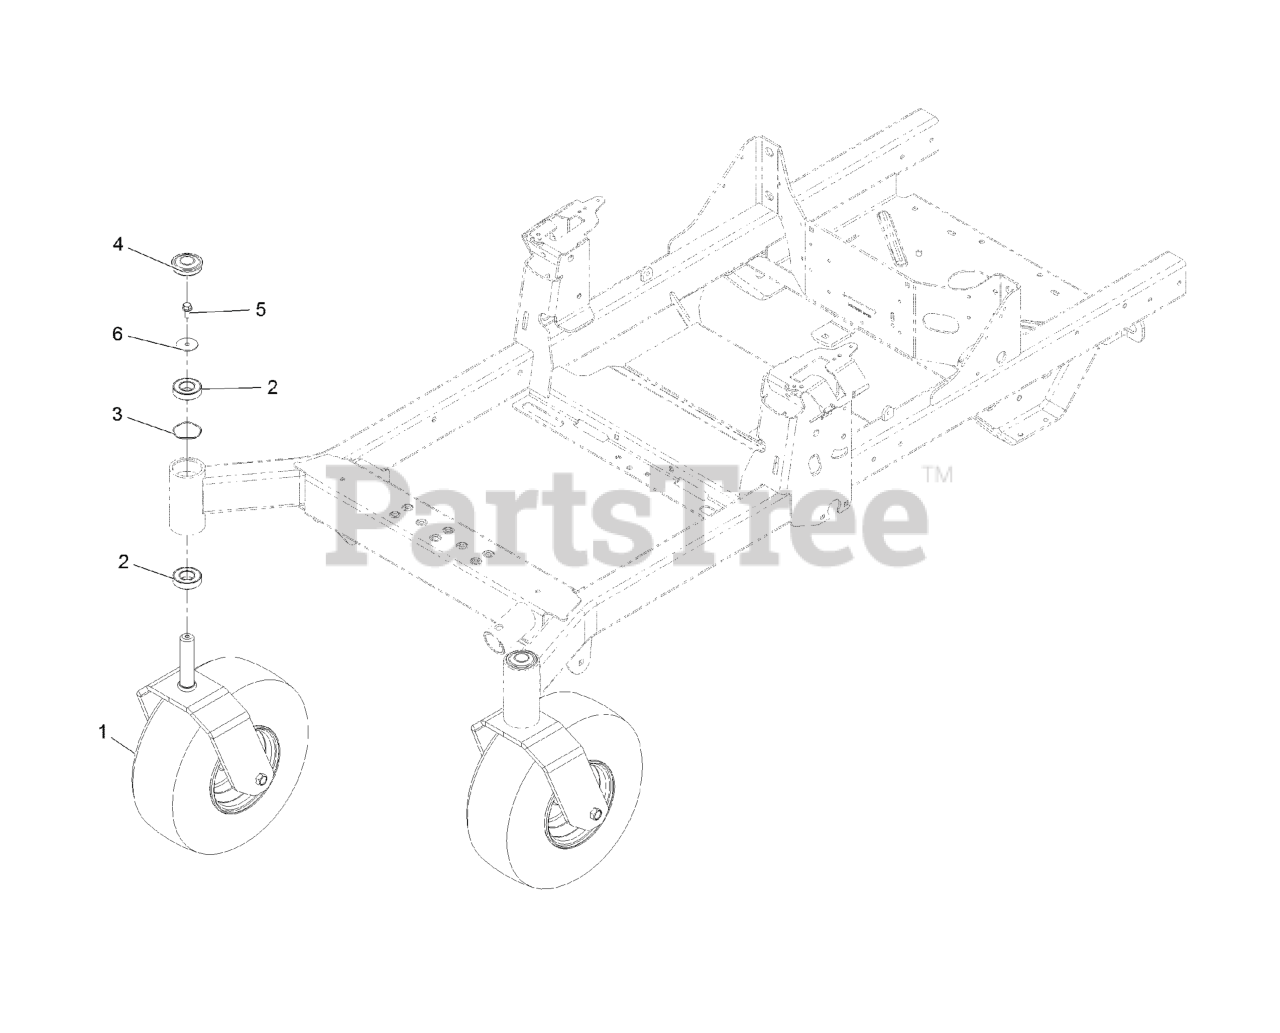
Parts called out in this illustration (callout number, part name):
1	ASM-Front Caster W/Fork
2	BEARING-BALL
4	CAP-GREASE
5	SCREW-HHF
6	WASHER-FLAT
